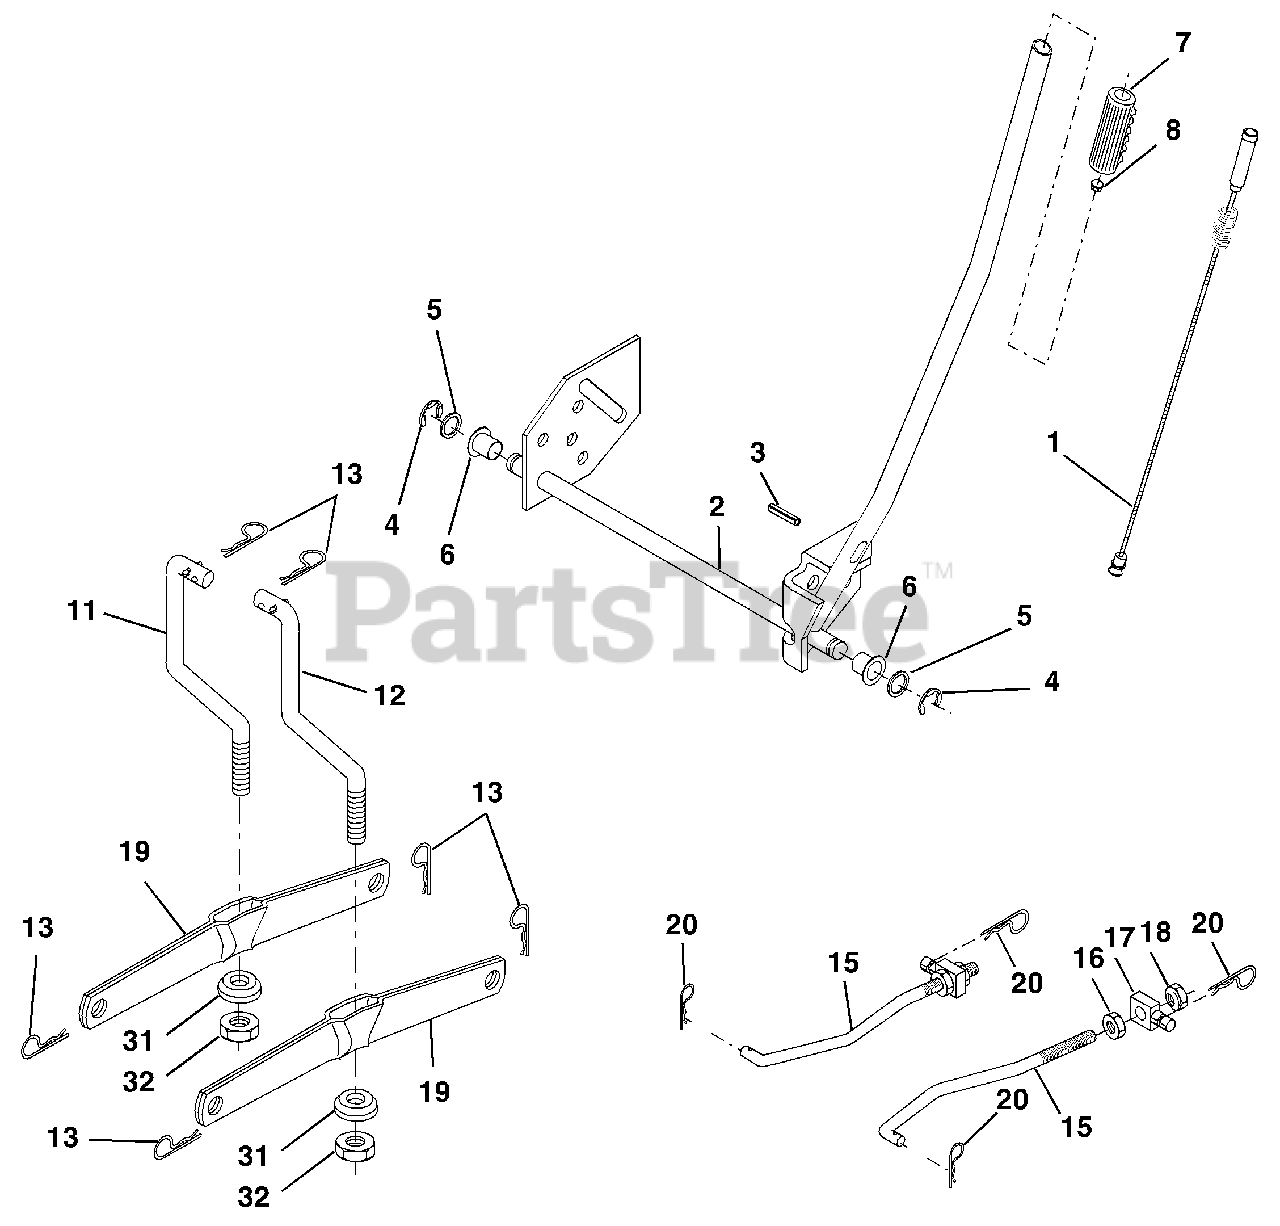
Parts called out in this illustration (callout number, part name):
1	Wire Asm Inner/Sprg w/Plunger
2	Shaft Asm Lift
3	Pin Groove
4	E Ring #5133-62
5	Washer 21/32 x 1 x 21 Ga.
6	Bearing Nylon
7	Grip Handle
8	Button Plunger
11	Link Lift Lh
12	Link Lift Rh
13	Retainer Spring
15	Link Front
16	Nut Jam Hex 1/2-13 Unc
17	Trunnion
18	Nut Lock w/Wsh 1/2-13 Unc
19	Arm Suspension Rear
20	Retainer Spring
31	Bearing Pvt Lift
32	Nut Crownlock 3/8-24
